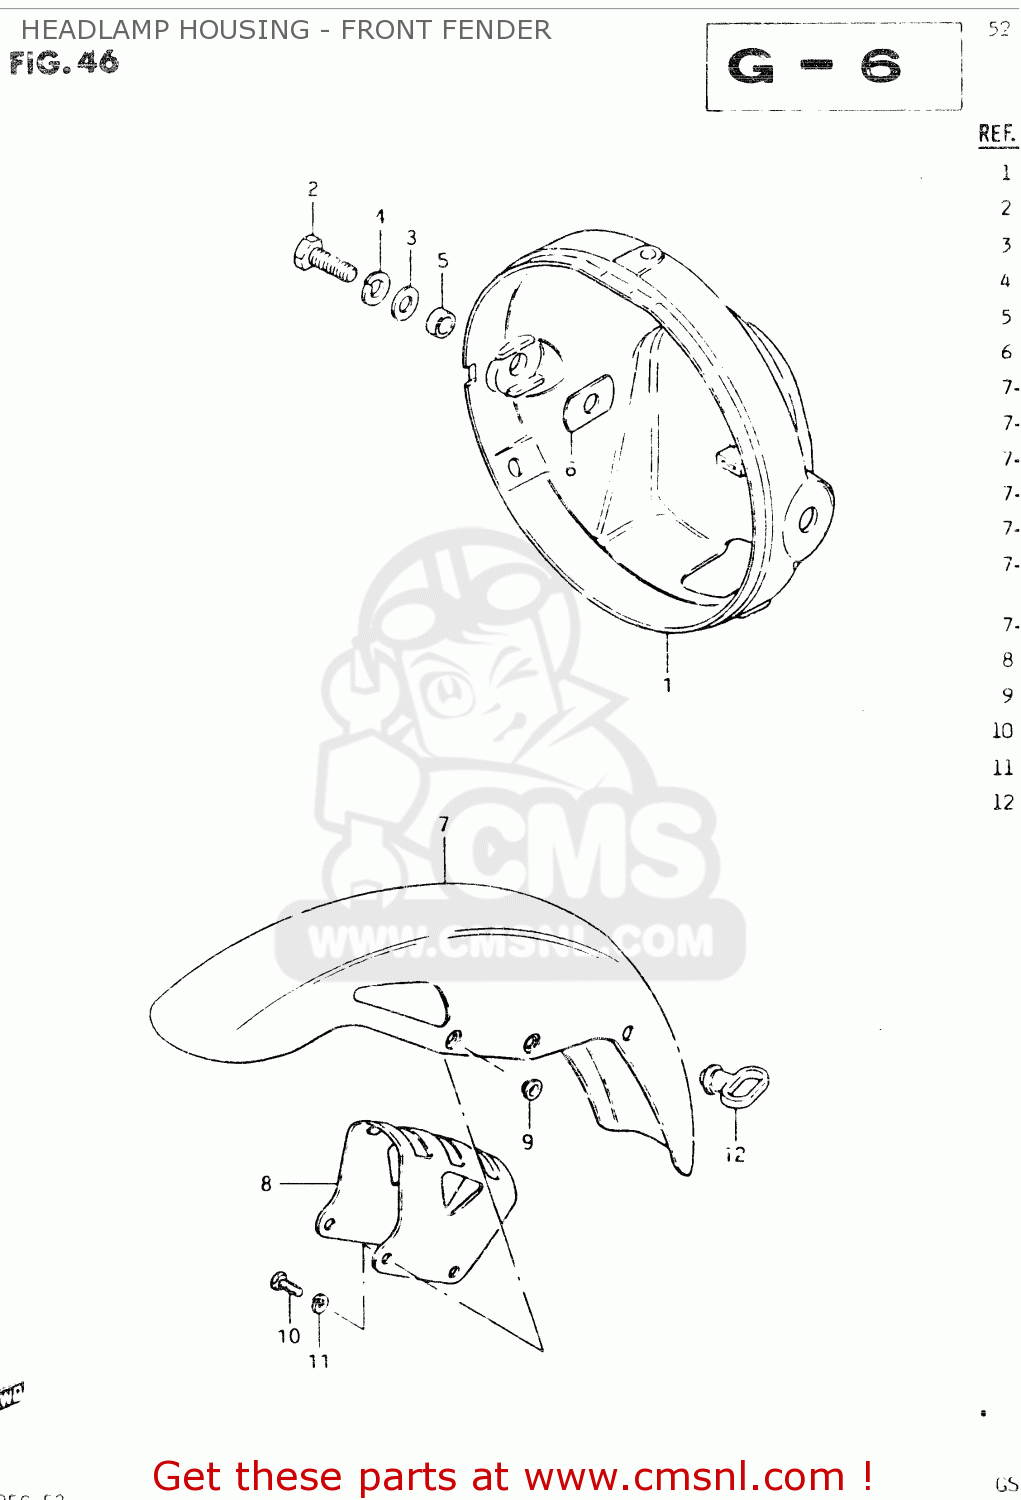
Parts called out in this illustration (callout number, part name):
1	HOUSING,HEADLAMP
2	BOLT
3	WASHER
4	LOCK WASHER
5	SPACER (8.8X12X7)
6	CUSHION
7	FENDER,FR
8	BRACE,FRONT FENDER
9	WASHER
10	BOLT
11	LOCK WASHER
12	GUIDE,CABLE
